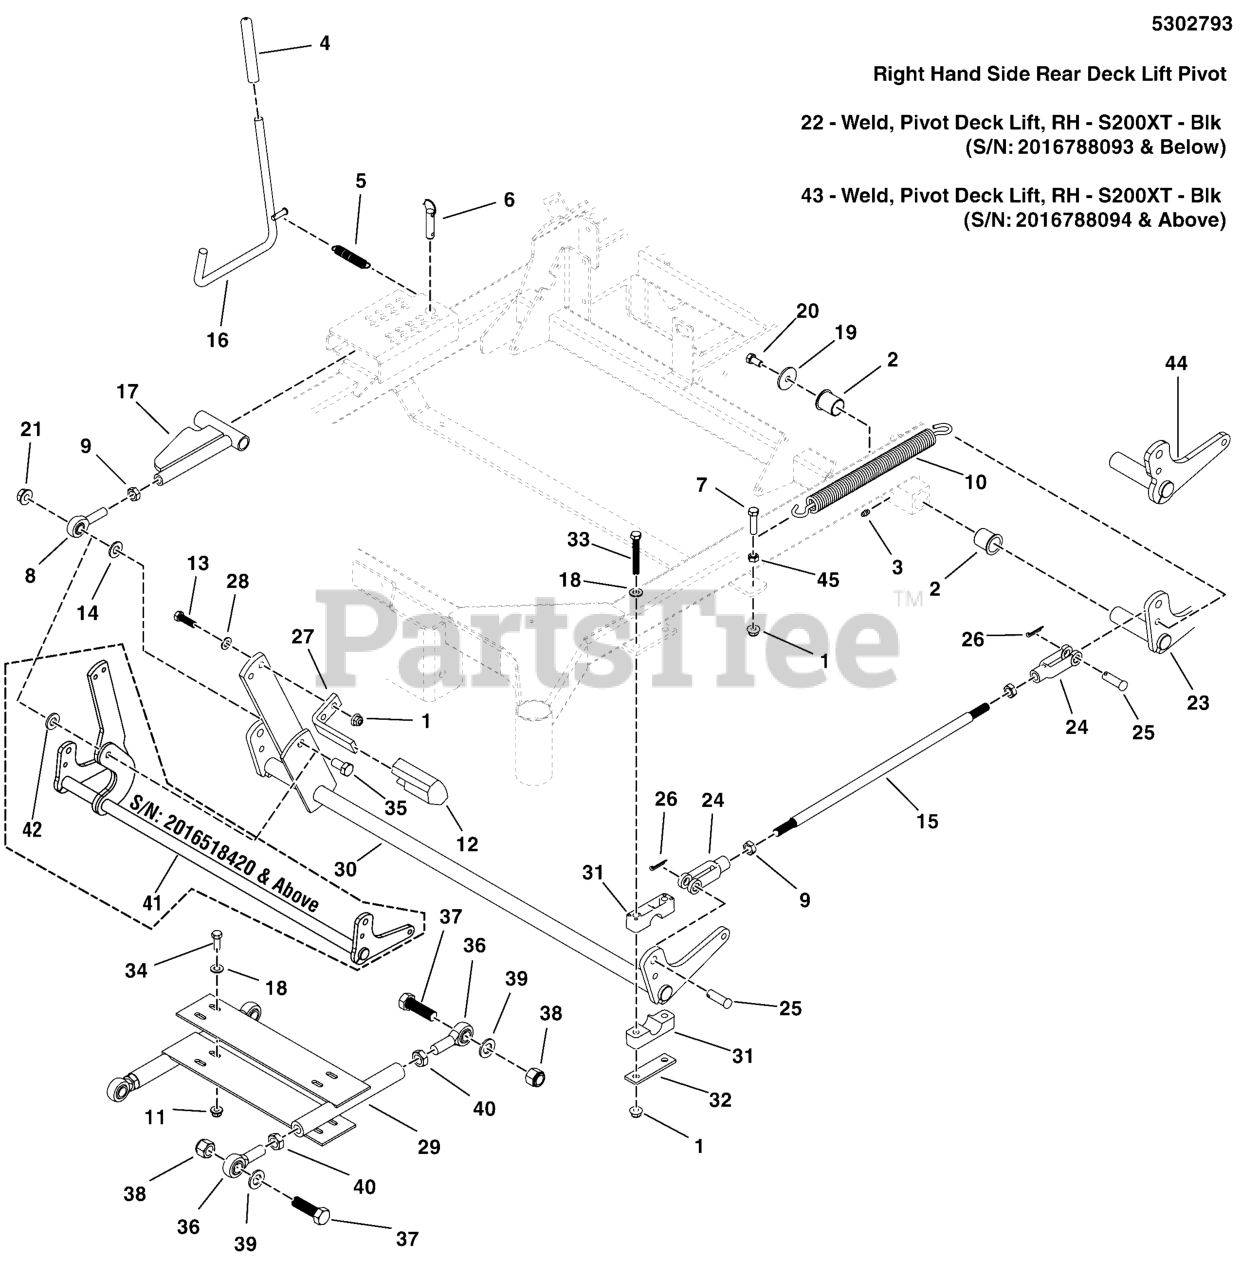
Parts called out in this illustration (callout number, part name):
1	NUT, 3/8-16 HEX NYLOCK FLANGE
2	BUSHING, 1.00 X 1.13 X 1.38, PLASTIC
3	GREASE FITTING, 1/4-28 STRAIGHT
4	GRIP, FOAM
5	SPRING, EXTENSION
6	PIN, HITCH, 1/2 X 2.00 OAL, YP
7	BOLT, 3/8-16 X 1-1/2" GD5 CZ
8	BALL JOINT, 1/2-20, MALE
9	NUT, 1/2-20 HEX JAM
10	SPRING, DECK LIFT ASSIST
11	NUT, 3/8-16 HEX SERRATED FLANGE
12	PEDAL, Rubber
13	BOLT, 3/8-16 X 1-1/4" GD5 CZ
14	WASHER, 1/2 SAE
15	ROD, DECK LIFT, TWR
16	WELD, ROD DECK LIFT - SNP RED
17	WELD, DECK ADJUST LINK - SNP RED
18	WASHER, 3/8 SAE
19	WASHER, .390 X 1.50 X .109, YZ
20	BOLT, 3/8-16 X 3/4, PLT W/PATCH
21	NUT, Hex Flange, Nylock, 1/2-13
22	WELD, PIVOT DECK LIFT, RH - S200XT - BLK
23	WELD, PIVOT DECK LIFT, LH - S200XT - BLK
24	CLEVIS, 1/2-20, STEEL
25	PIN, CLEVIS, 1/2 X 1 1/2, YZP
26	PIN, COTTER, 1/8 X 3/4
27	PEDAL, FOOT - BLK
28	WASHER, 3/8 GD.9 FLAT
29	WELD, DECK STABILIZER - BLK
30	WELD, DECK LIFT SHAFT, S200XT - RED
31	PIVOT BLOCK, PLASTIC
32	PLATE, PIVOT BLOCK SUPPORT - BLK
33	BOLT, 3/8-16 X 2-3/4" GD5 CZ
34	BOLT, 3/8-16 X 1" GD5 CZ
35	BOLT, 1/2-13 X 1-1/4 GD5 CZ
36	BALL JOINT, 3/4-16, MALE
37	BOLT, 3/4-16 X 2-1/2 YZ GD5
38	NUT, 3/4-16 HEX NYLON LOCK
39	WASHER, 3/4 SAE
40	NUT, 3/4-16 HEX JAM
41	WELD, DECK LIFT SHAFT, 200XT-61 - RED
42	SPACER, .52 X 1.00 X .22, PM, CZ
43	WELD, PIVOT, DECK LIFT, RH, 200XT - BLK
44	WELD, PIVOT, DECK LIFT, LH, 200XT - BLK
45	NUT, 3/8-16 HEX JAM
